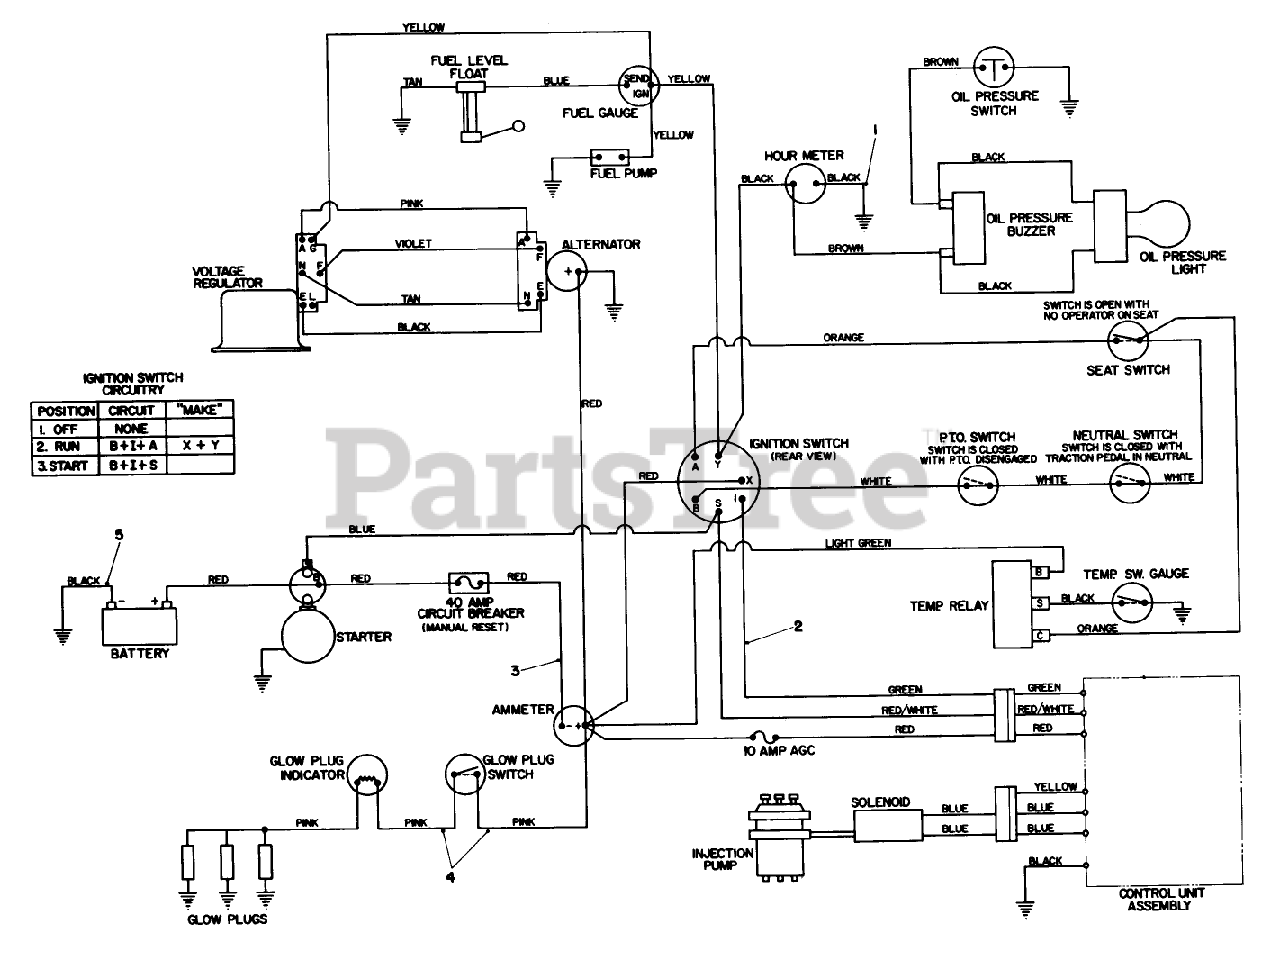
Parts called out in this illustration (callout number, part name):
1	Wire Harness
2	WIRE HARNESS ASM
3	WIRE ASM
5	BATTERY GROUND CABLE
